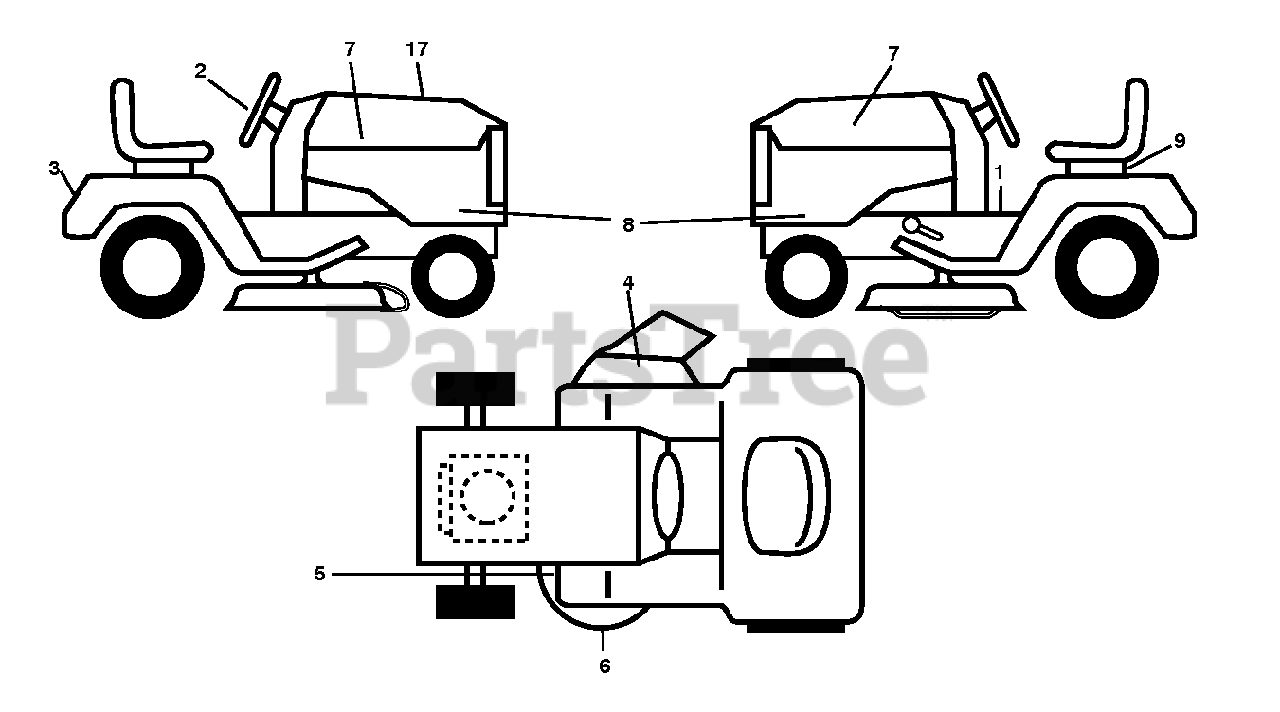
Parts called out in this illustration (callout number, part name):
1	DECAL.FENDER.WARNING.ENGLISH
2	Decal, Steering Wheel STDXXSQ PPRO 2015
3	DECAL.REARFNDR.POULAN PRO.2015
4	DECAL, DECK DEFLECTOR, WARNING
5	DECAL.V-BELT.SCH.42/46"MEC/ELE
6	DECAL.ENG.BS.18INTK.DOM.381706
7	DECAL.POULAN PRO.2015
8	DECAL.SDPNL.PB20A46.BLK.PPRO
9	DECAL BTRY SYMBOLS
